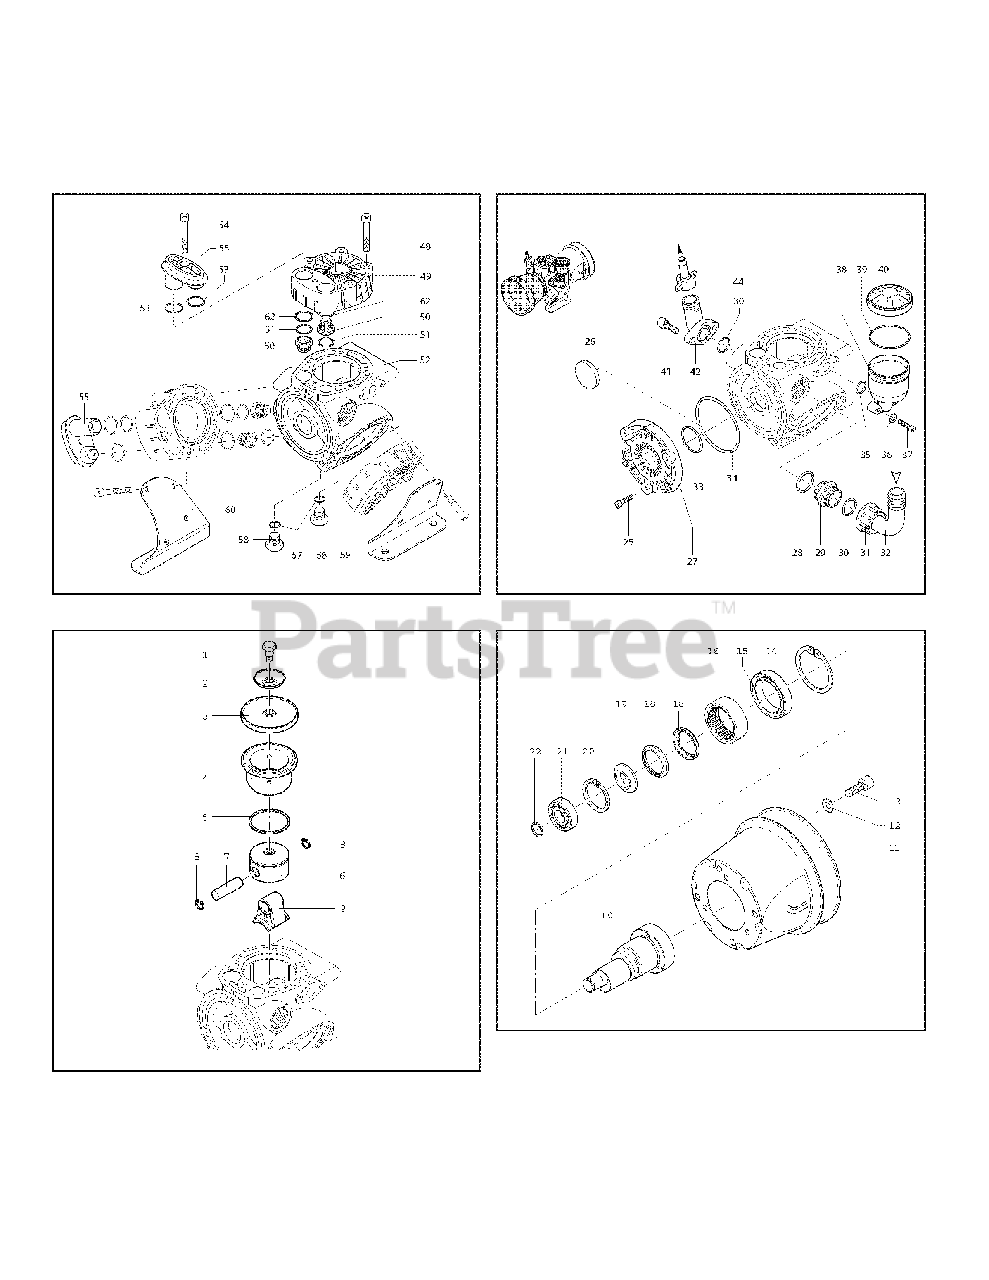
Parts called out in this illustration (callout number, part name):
1	Retaining Bolt
3	Diaphragm Desmopan (Std.)
3	Diaphragm Buna-N (Opt.)
9	Connecting Rod
13	M10 X 16 Bolt
14	Retaining Ring
16	Roller Bushing
18	Connecting Rod Ring
20	Retaining Ring
22	Retaining Ring
27	Suction Manifold
29	Threaded Adapter
32	Elbow (Hose Barb)
38	Oil Sight Glass
40	Black Oil Tank Cap
44	1/2" Fitting and Hose
50	Complete Valve Assembly
55	Right Valve Cover
58	Drain Plug, oil
